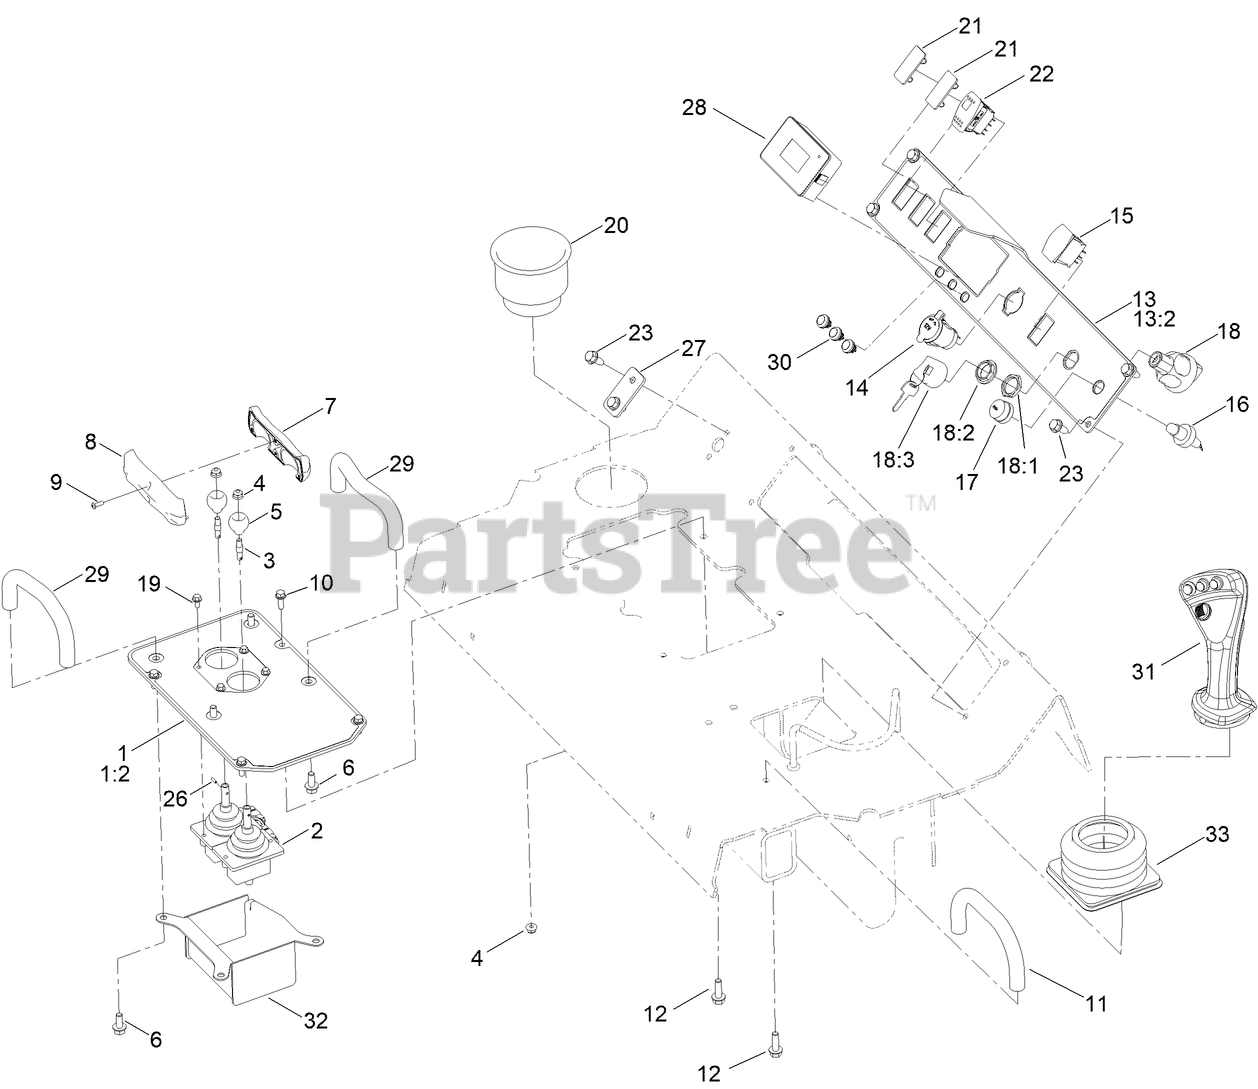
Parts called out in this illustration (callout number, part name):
1	PLATE-CONTROLS, TRACTION
1:2	DECAL-TRACTION
2	LEVER-CONTROL
3	SHAFT-HANDLE
4	NUT-HF
5	BALL-TRACTION
6	SCREW-HHF
7	HANDLE-FRONT
8	HANDLE-REAR
9	SCREW
10	SCREW-HHF
11	BAR-REFERENCE
12	SCREW-HHF
13	PLATE-CONTROL, MAIN
13:2	DECAL-CONTROLS
14	PORT-POWER, 12V
15	SWITCH
16	SWITCH-HORN
17	NUT-WEATHERPROOF
18	IGNITION SWITCH ASM
18:1	NUT-HEX
18:2	NUT-FACE, M22 (PLASTIC)
18:3	SET-KEY, IGNITION
19	SCREW-HFH
20	CUP-HOLDER
21	PLUG-HOLE
22	SWITCH
23	SCREW-HWH
26	PIN-ROLL
27	PLATE-BLANK
28	TDM 2002
29	BAR-REFERENCE
30	SWITCH-PUSHBUTTON
31	HANDLE-JOYSTICK,
32	COVER-VALVE
